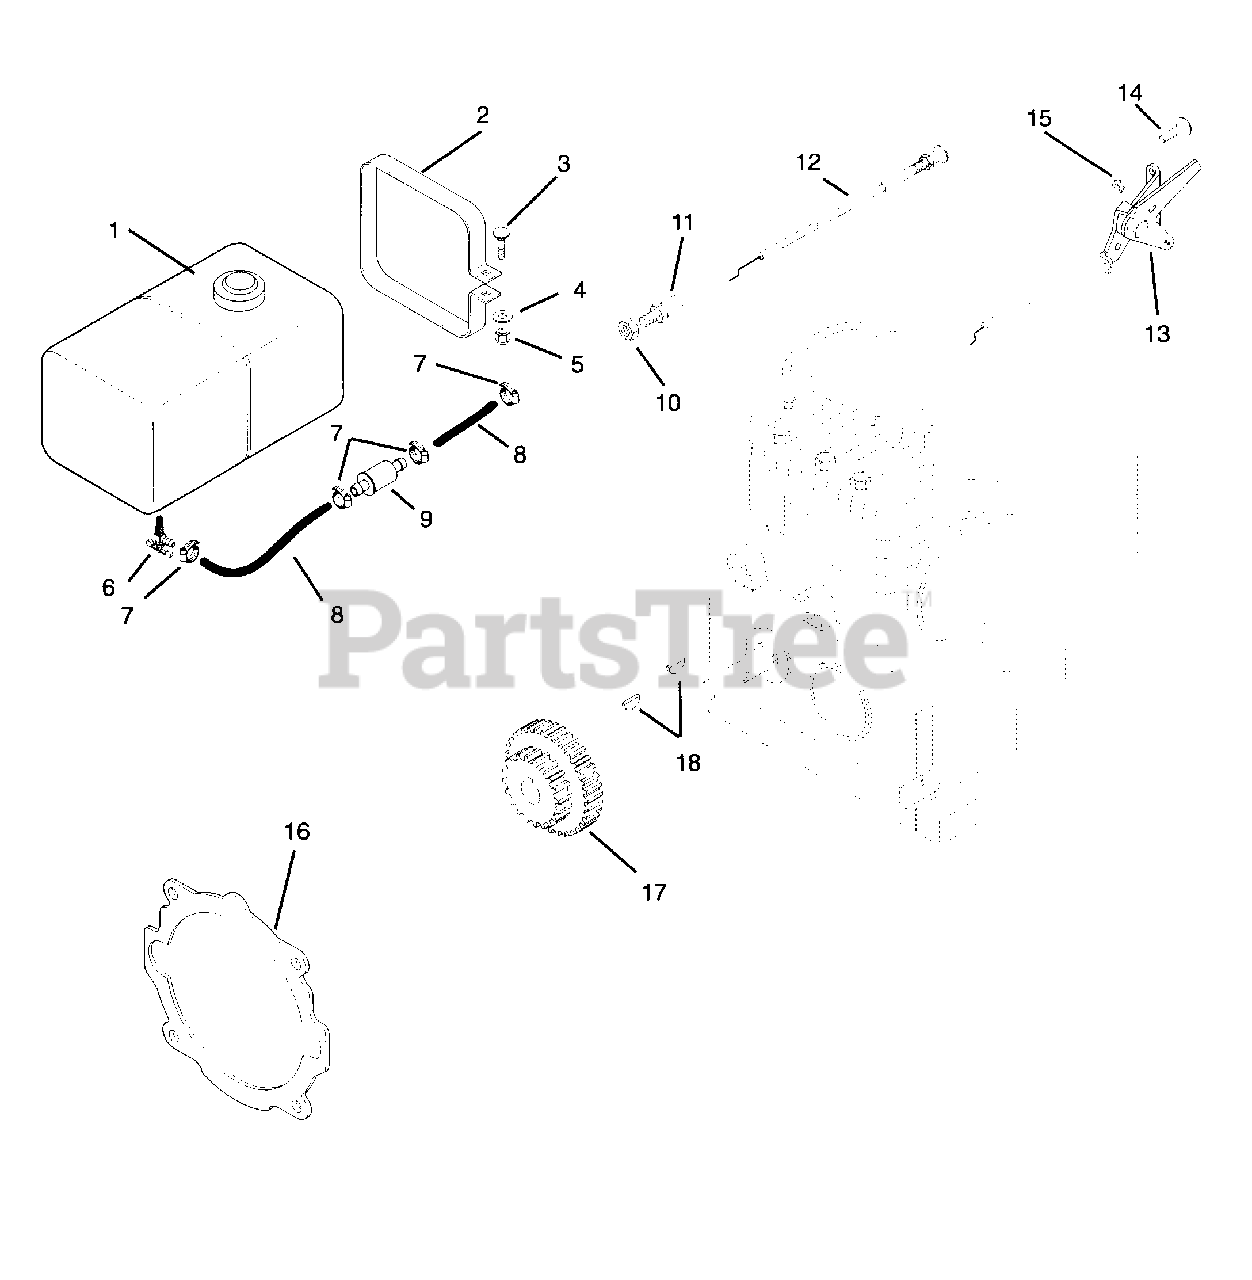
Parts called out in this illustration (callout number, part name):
1	Tank, Fuel w/Cap
2	Strap, Fuel Tank
3	Bolt-Round Head Square Neck .25-20 x 1.75
4	Washer-Flat-Steel .281 x .62
5	Nut-Lock-Center .250-20
6	Valve and Strainer
7	Hose Clamp
8	Gas Line-Bulk
9	Filter, Fuel
10	Nut-Hex .250-20
11	Adapter, Conduit
12	Lever, Choke Control
13	Lever, Throttle
14	Screw-Machine 10-24 x .50
15	Nut-Lock Nylon 10-24
16	Gasket, Chassis to Adapter
17	Gear, 10/12 DP 21/30 Teeth
18	Key, Woodruff .16 x .63
